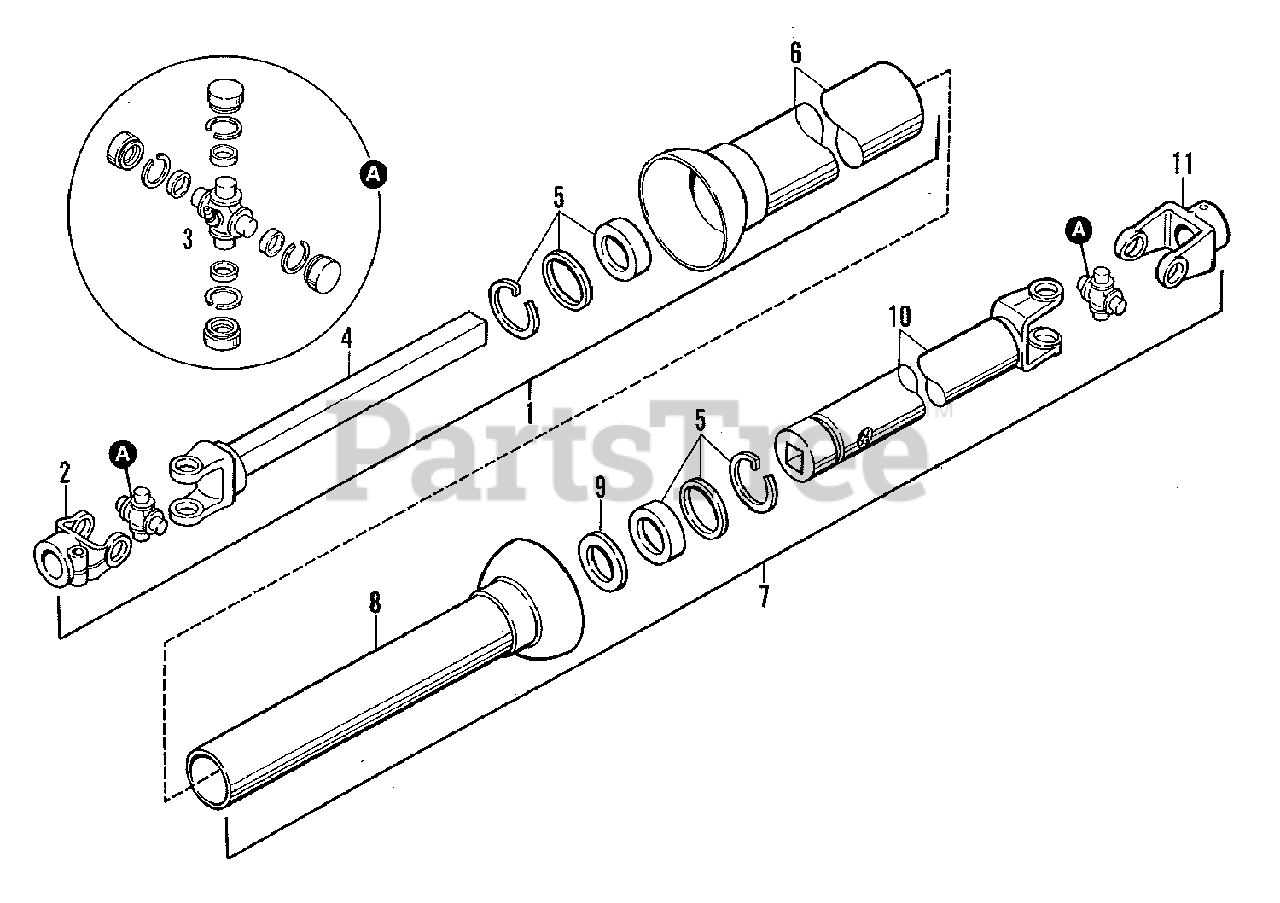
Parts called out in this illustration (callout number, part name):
1	PTO ASSEMBLY, Tractor End (Use 2018551 PTO Assembly)
1	PTO ASSEMBLY, Tractor End
2	YOKE, Tractor End
3	U-JOINT KIT
3	FITTING, Lube, Special Shoft, 1/4 x 65 Degrees
4	SHAFT & YOKE ASSEMBLY
6	SHIELD, Outer (Use SHIELD 2108557)
6	SHIELD, Outer
7	PTO ASSEMBLY, Implement End
8	SHIELD, Inner
9	BEARING, Nylon
10	TUBE & YOKE ASSEMBLY (Use TUBE & YOKE ASSEMBLY 2108559)
10	TUBE & YOKE ASSEMBLY
11	YOKE, Implement End
11	CAPSCREW, Socket Head, 3/8NC x 2-1/2, Gr. 8
11	NUT, Lock, Flange, 3/8NC
11	YOKE, Implement End (Type l)
11	YOKE, Implement End (Type ll)
11	CAPSCREW, Socket Head, 3/8NC x 2, Gr. 8
